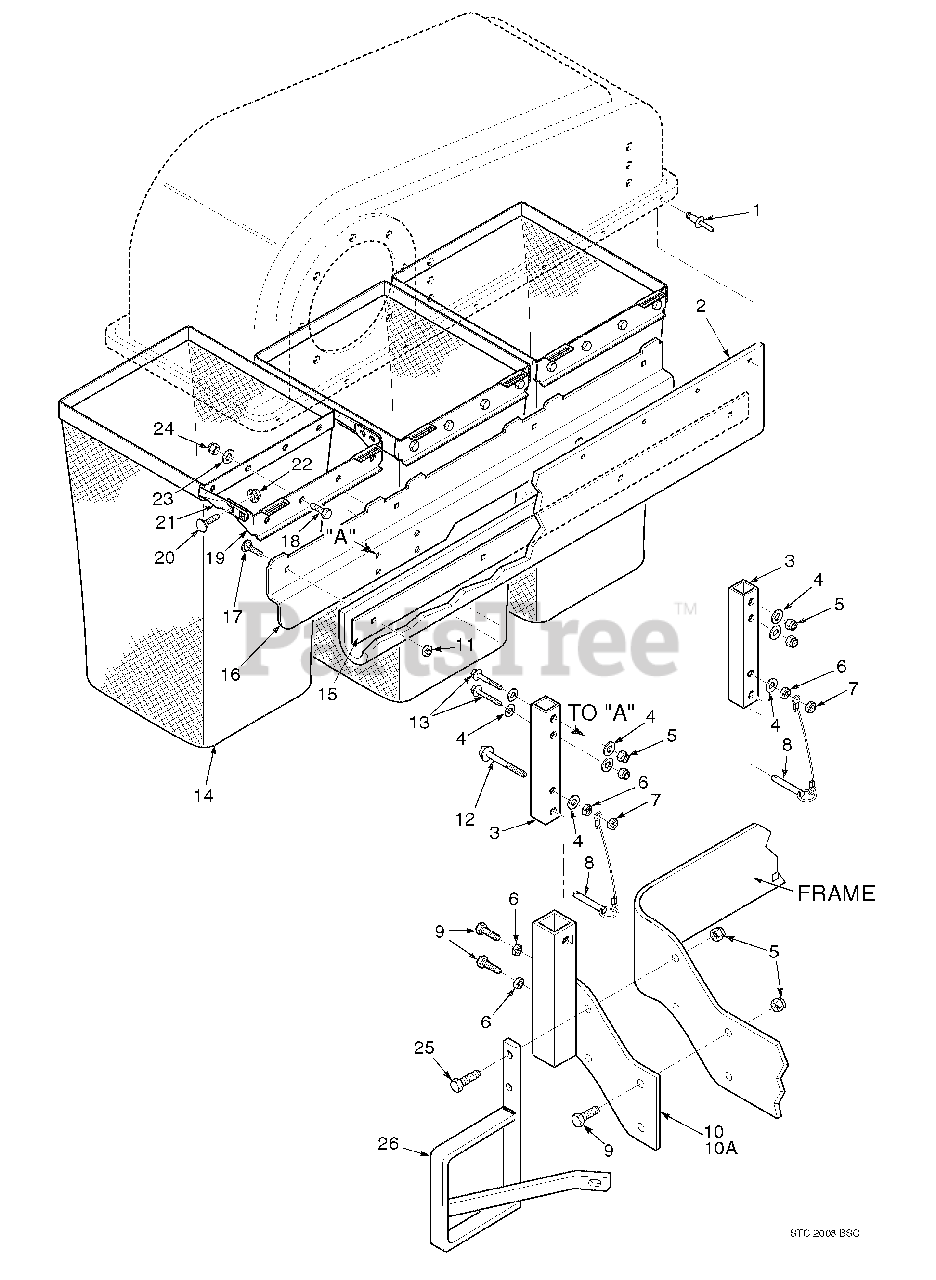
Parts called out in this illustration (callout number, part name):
1	Pop Rivet, 3/16 x .652
2	Seal, Hood
3	Tube, Upright
4	Flatwasher, 3/8-.391 x .938 x .105
5	Nut, Elastic Stop 3/8-16
6	Nut, 3/8-16
7	Hex Lock Nut, 3/8-16
8	Pin, Ring 1/2 x 2-1/4"
9	Bolt, Hex Head 3/8-16 x 1"
10	Mounting Bracket Weldment RH
10A	Mounting Bracket Weldment LH
11	Lock Nut, 1/4-20 Center
12	Bolt, Hex Head 3/8-16 x 2-1/4"
13	Bolt, Hex Head 3/8-16 x 2-1/2"
14	Bag Assembly, GC-STT
15	Retainer, Seal
16	Support, Bag Frame
17	Bolt, Carr. 1/4-20 x 3/4"
18	Bolt, Hex Head 5/16-18 x 3/4"
19	Mount, Bag Frame Tube
20	Bolt, Carr. 5/16-18 x 3/4"
21	Tube, Bag Support
22	Nut, Serr. Flange 5/16-18
23	Flatwasher, 5/16-.375 x .875 x .083
24	Nut, Elastic Stop 5/16-18
25	Bolt, Hex Head 3/8-16 x 1-1/4"
26	Muffler Guard
